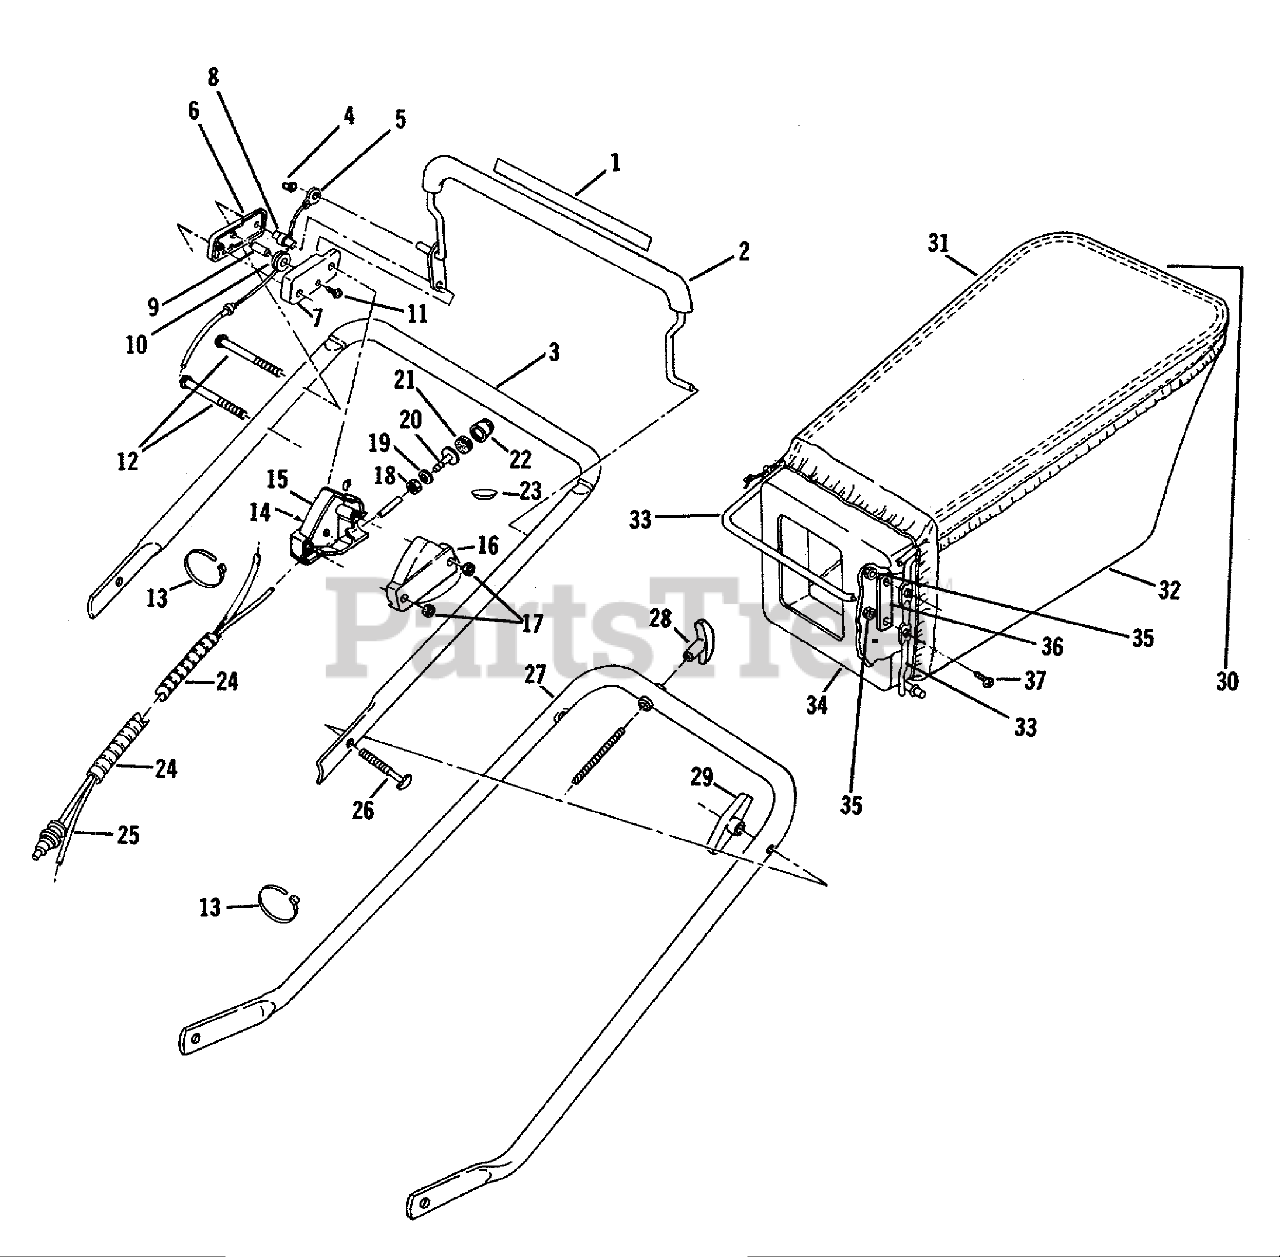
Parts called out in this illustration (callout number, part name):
5	CONTROL CABLE AY
8	COLUMN
9	PIN SKF
11	SCREW
17	NUT C/LOCK E
18	LOCKNUT S
21	FILTER S
25	PRIMER TUBING
26	BOLT QUALITY
28	HANDLE,STARTER
29	NUT-WING
31	HANGER BAG TROX
34	BAG ADAPTOR PL
35	LOCKNUT E
